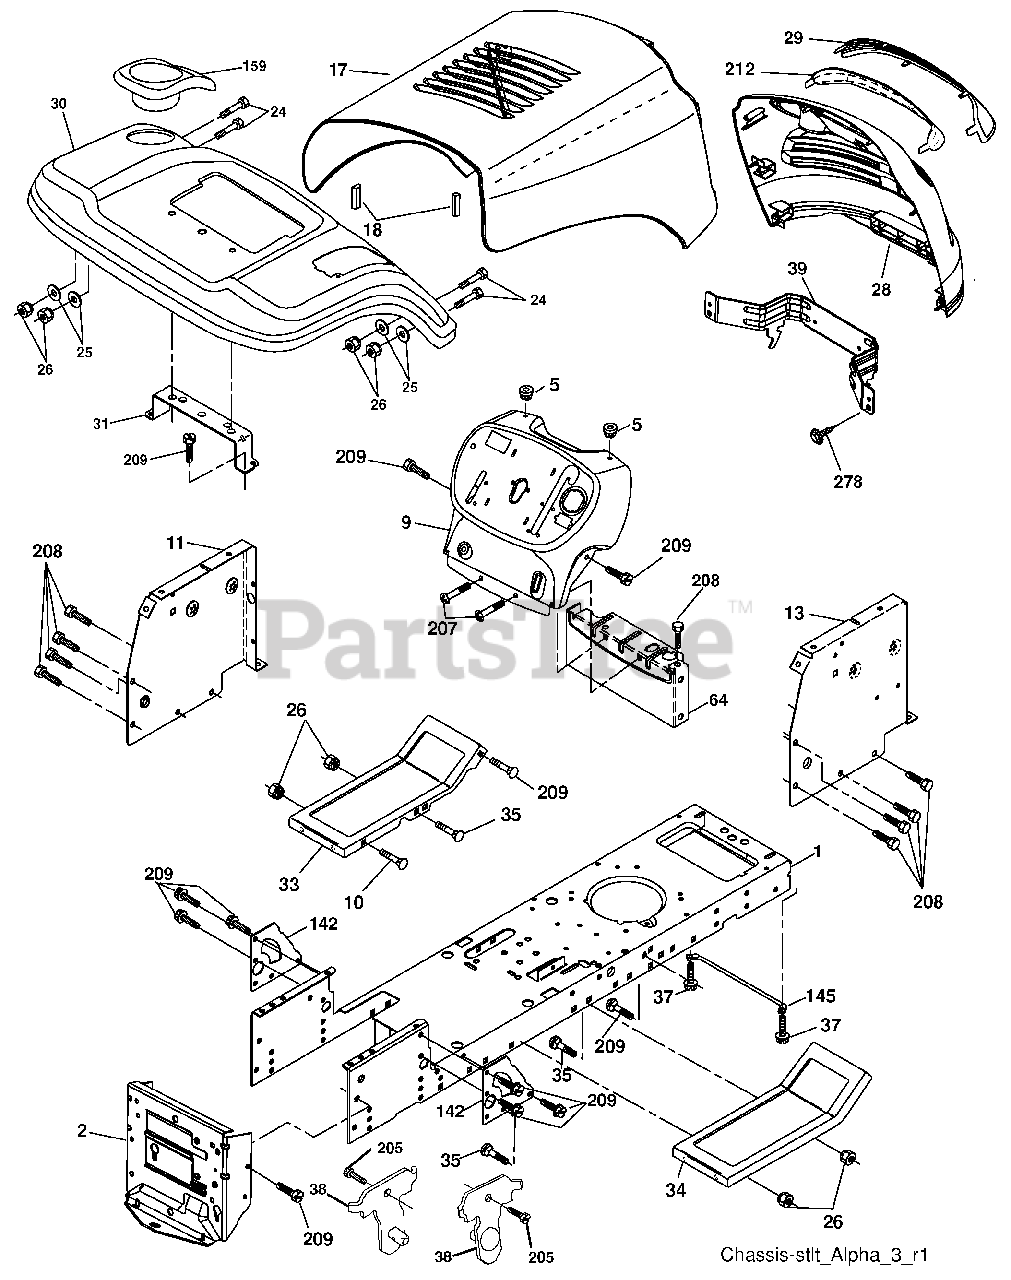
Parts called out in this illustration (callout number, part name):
1	Chassis
2	Drawbar, Stretch
5	Bumper, Hood/Dash
9	Dash
10	Bolt, Carriage 3/8-16 x 1
11	Panel Dash LH
13	Panel Slkscr Dash RH
17	Hood
18	Bumper Hood
24	Bolt Fin Hex 3/8-16 unc x 1 Gr. 5
25	Washer 13/32 x 13/16 x 12 Ga.
26	Nut Lock Hex w/Ins 3/8-16 unc
28	Grille
29	Lens Grille Bar
30	Fender
31	Bracket Fender Repl 109873X
33	Footrest Pnt LH
34	Footrest Pnt RH
35	Bolt Rdhd Sht Sqnk 3/8-16 x 3/4
37	Screw Thdrol 5/16-18 x 1/2 TYT
38	Bracket Asm. Pivot Mower
39	Bracket Pivot
64	Dash Lower
142	Plate Reinforcement
145	Rod Pivot Chassis/Hood
159	Cupholder
205	Screw Thdrol 3/8-16 x 1/2
207	Screw 5/16-18 x 1/2
208	Screw Thdrol 3/8-16 x 1/2
209	Screw Hex Wsh Thdrol 3/8-16
212	Insert Lens Reflect
278	Screw #10 x 0.750 BOS Thread
278	Plug Button Blk 359 Dia Choke
278	Plug Dome Plastic
